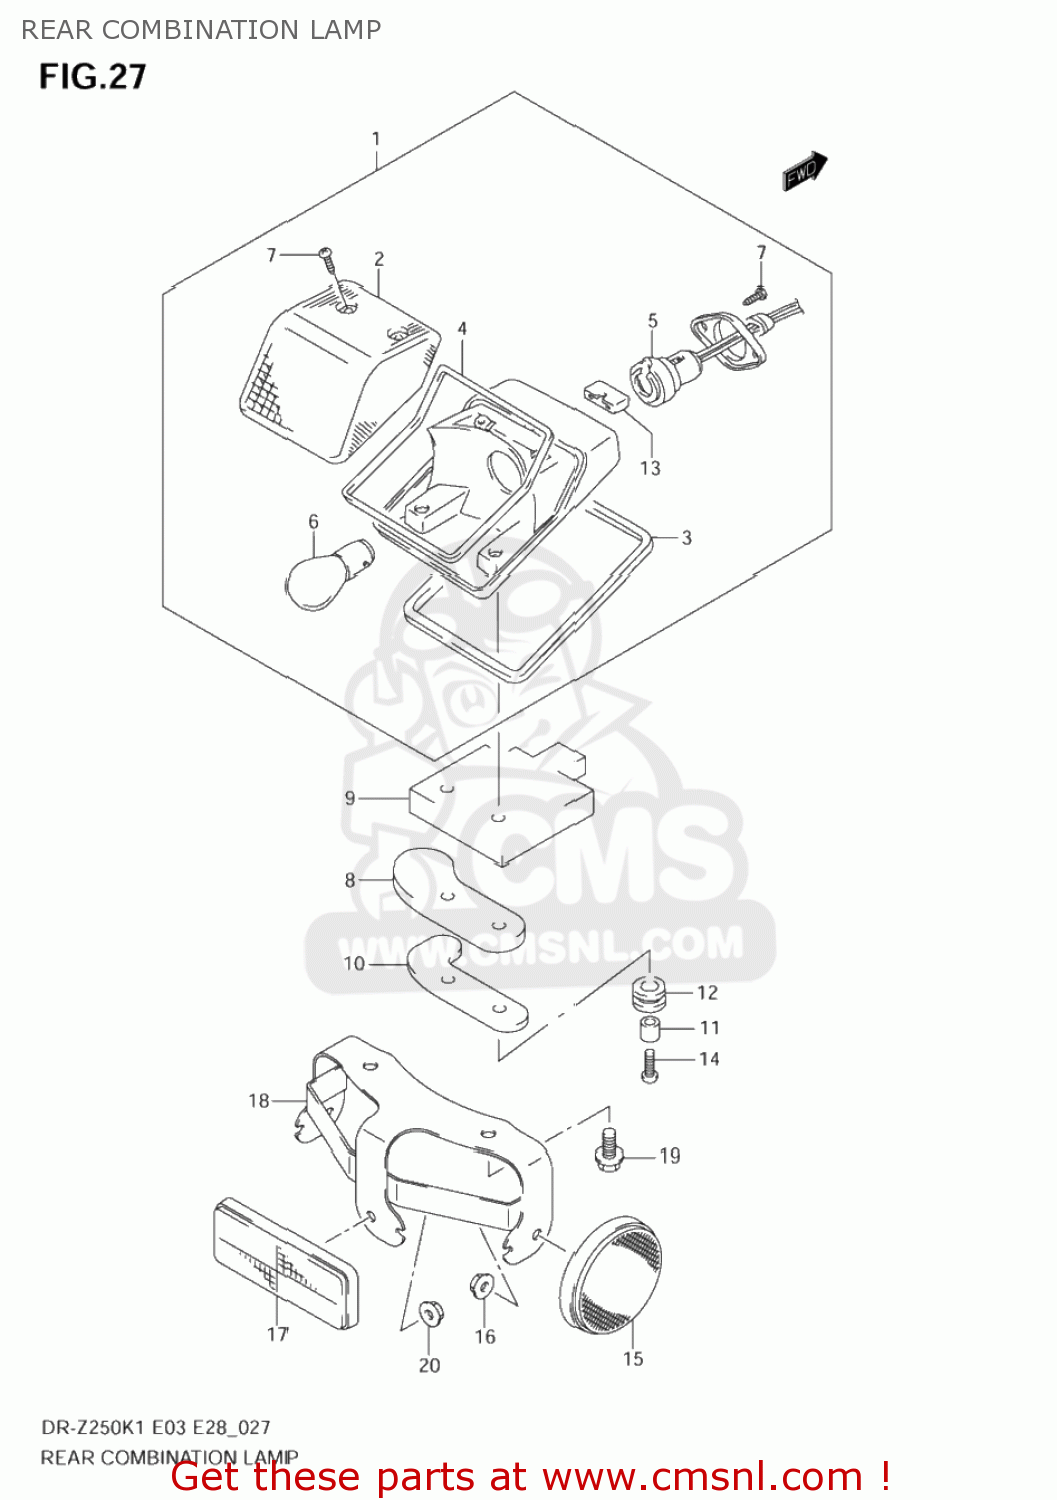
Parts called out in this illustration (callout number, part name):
1	LAMP ASSY, REAR COMB
2	LENS
3	GASKET
4	GASKET
5	SOCKET & CORD
6	BULB(12V21/5W)
7	SCREW
8	CUSHION,BRACKET
9	CUSHION,LWR
10	BRACKET,RR COMBI LAMP LWR
11	SPACER(6.5X9X12.5)
12	CUSHION
13	CUSHION
14	SCREW, 6X20
15	REFLEX REFLECTOR,RR
16	NUT
17	REFLECTOR ASSEMBLY,REAR
18	BRACKET,SIDE & RR RR
19	BOLT
20	NUT
